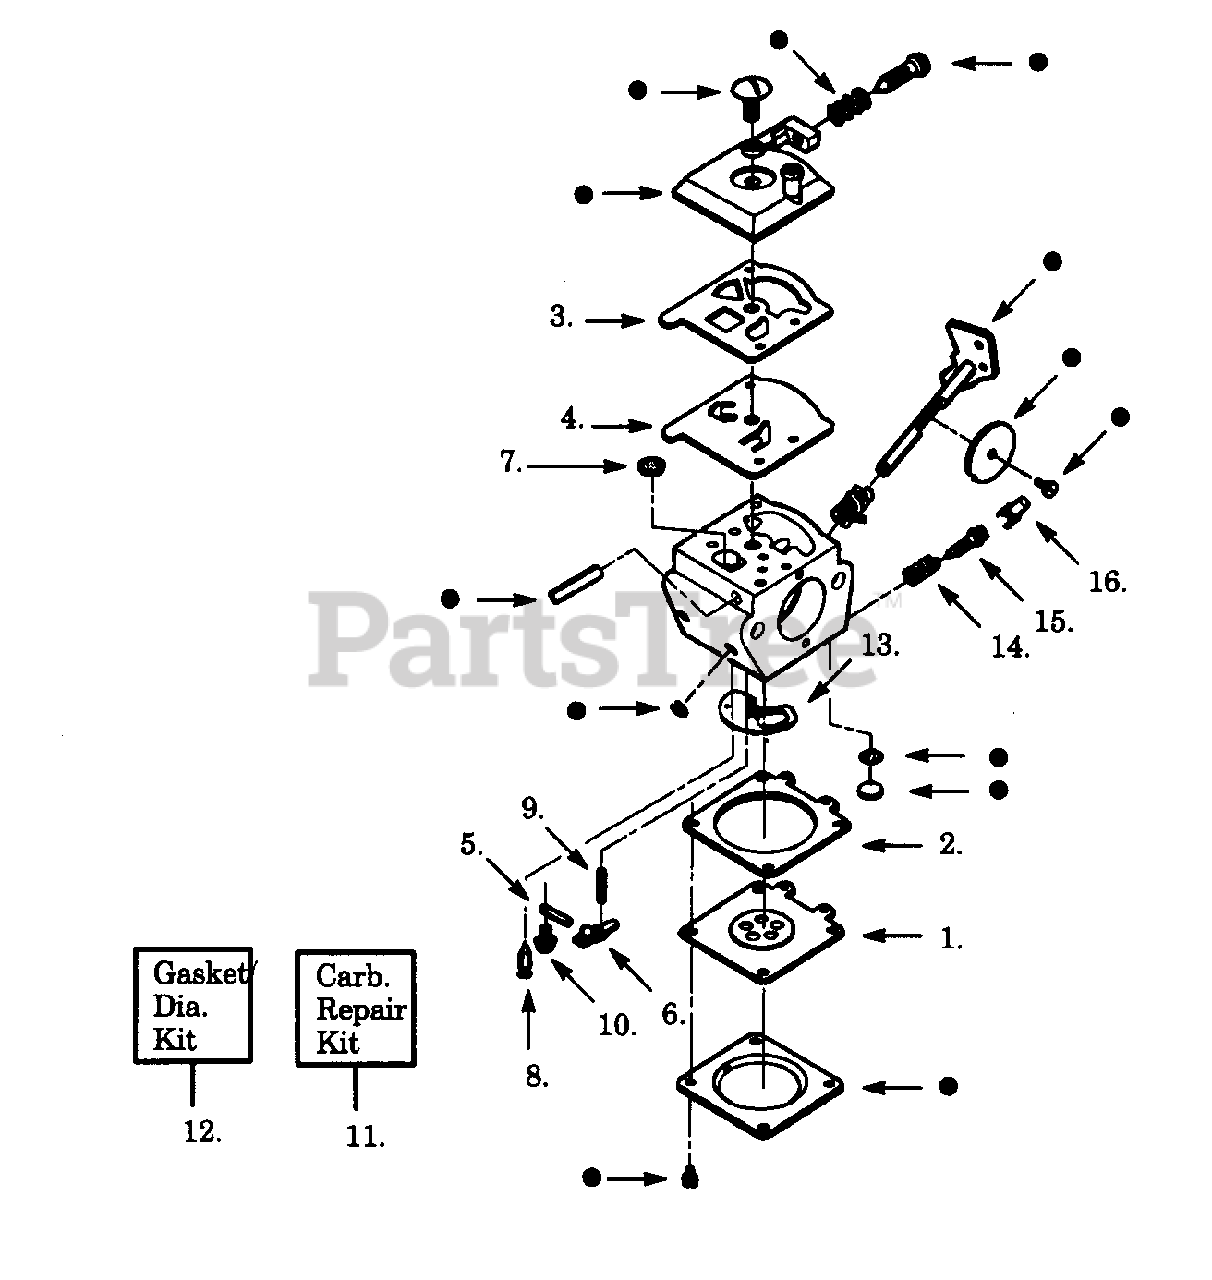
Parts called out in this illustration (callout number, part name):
1	Metering Diaphragm
2	Metering Diaphragm Gasket
3	Pump Gasket
4	Pump Diaphragm
5	Metering Lever Pin
6	Metering Lever
7	Fuel Inlet Screen
8	Inlet Needle Valve
9	Metering Lever Spring
10	Metering Lever Pin Screw
11	Carburetor Repair Kit
12	Gasket/Diaphragm Kit
13	Circuit Plate Gasket
14	Spring-Idle Needle-Type II
15	Idle Needle-Type II
16	Limiter Cap-Type II
